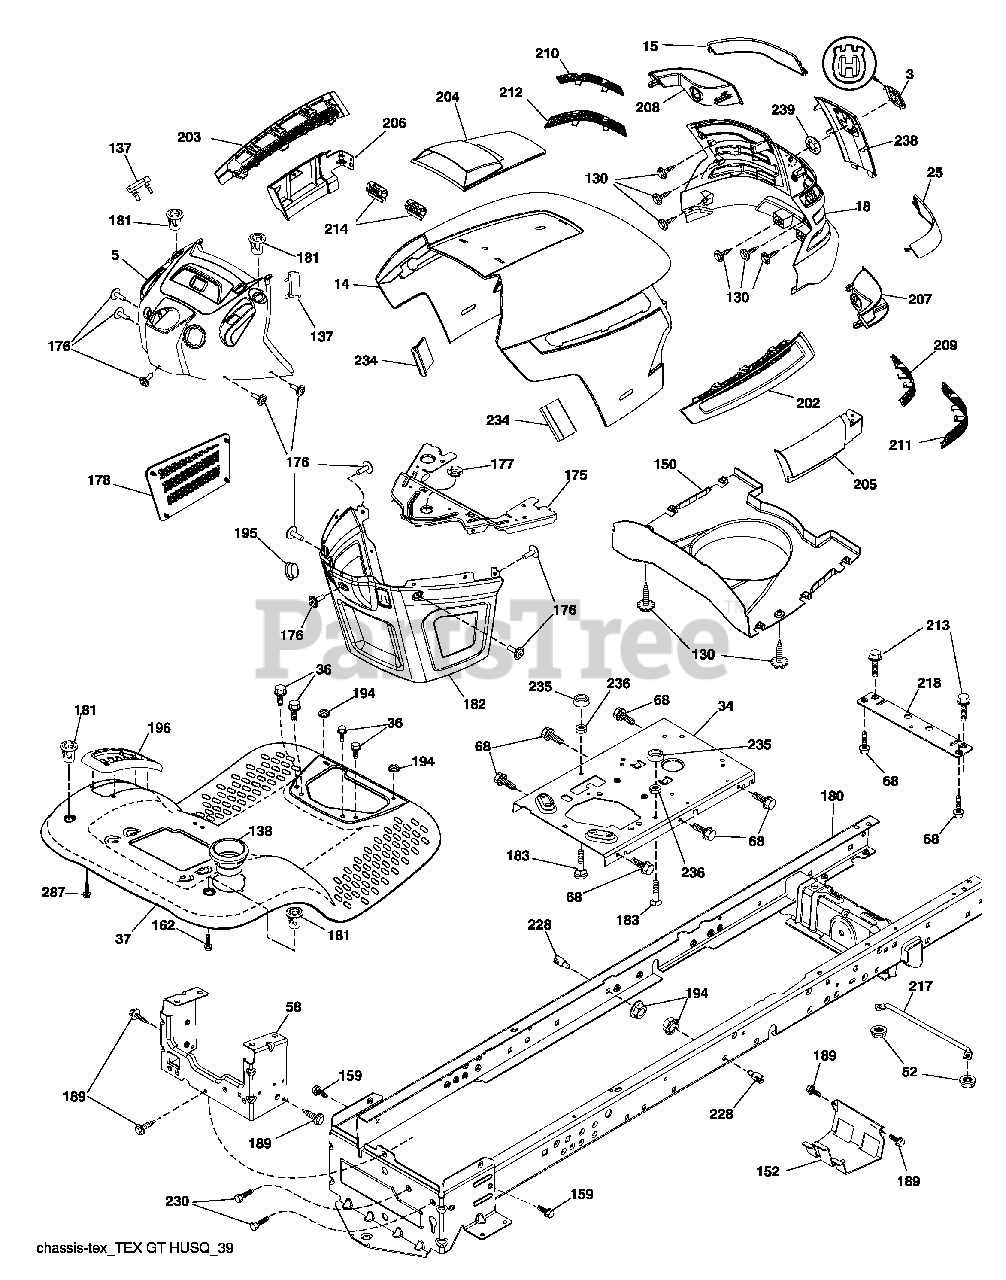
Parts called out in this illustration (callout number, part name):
3	Logo
5	Dash Asm. Husq.
14	Hood
18	Grille Asm.
34	Plate Engine
36	Screw 5/16-18 x 3/4
37	Fender
52	Nut Lock 5/16-18
58	Drawbar Upper
68	Screw Thdrol 5/16-18 x 1/2
130	Screw #10 x 0.750
137	Bumper Dash
138	Cupholder
152	Shield Browning
159	Screw 3/8-16 x 3/4
175	Crossmember
176	Screw 10-24 x 5/8
177	Bushing Steering
178	Cargo Net Asm.
181	Bushing Mtg. Fender Crgo
182	Dash Lower
183	Bolt Fin Hex 5/16-18 unc x 1-1/4
189	Screw 5/16-18 x 3/4
194	Nut Lock Hex Flange 5/16-18
195	Plug Hole Dash Lower
196	Console Asm. Deck Lift
202	Vent Side Hood RH
203	Vent Side Hood LH
204	Vent Top Hood
205	Skirt Hood Side RH
206	Skirt Hood Side LH
209	Insert Hex Top RH
210	Insert Hex Top LH
211	Insert Hex Bottom RH
212	Insert Hex Bottom LH
213	Bolt 5/16-18 x 3/4
214	Clip Retainer Tinner
218	X-Piece Hood Stop
228	Stud Fastner
230	Bolt Shoulder 5/16-18
234	Bumper Hood
235	Spacer Fender
236	Nut Lock 5/16-18 unc
287	Screw 1/4-20 x 3/8
